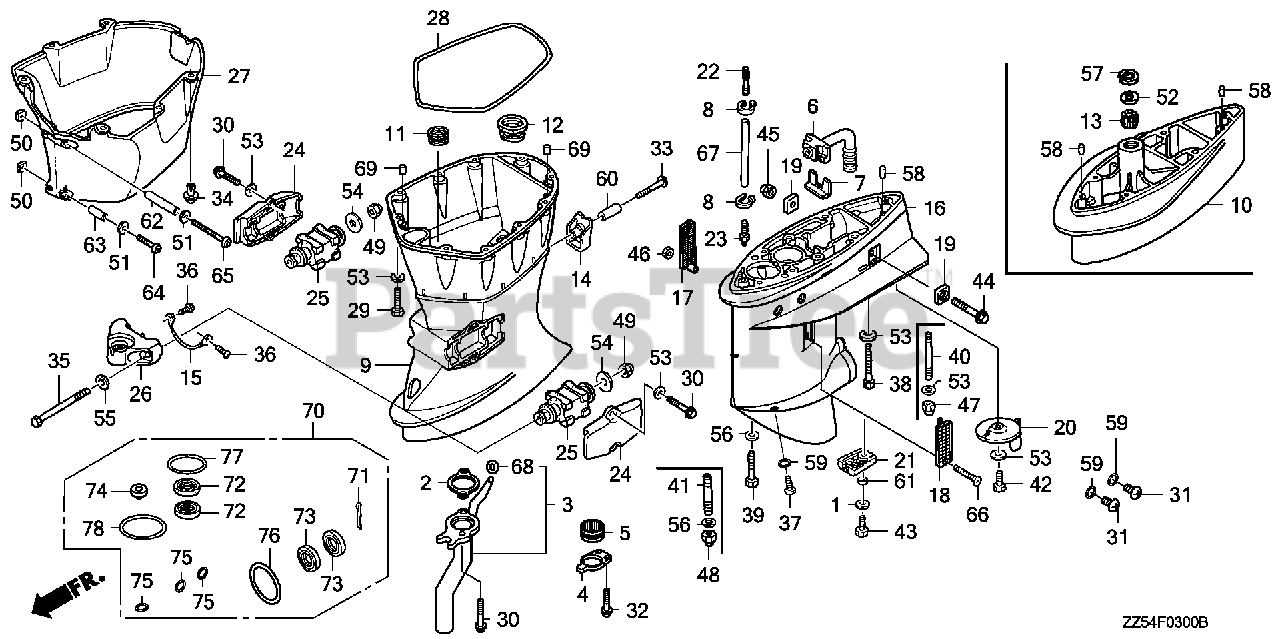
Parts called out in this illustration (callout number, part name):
1	WASHER, PIVOT
2	GASKET, EX. PIPE
3	PIPE KIT, EX.
4	HOLDER, EX. PIPE GROMMET
5	GROMMET, EX. PIPE
6	TUBE, WATER (LOWER)
7	PLATE, RUBBER SETTING
8	BAND, WIRE
9	CASE, EXTENSION *NH282MU* (OYSTER SILVER METALLIC-U)
10	SEPARATOR, EXTENSION *NH282MU* (OYSTER SILVER METALLIC-U)
11	GROMMET, EXTENSION CASE
12	RUBBER, DRAIN PLUG
13	BUSH, VERTICAL SHAFT
14	COVER, DRAIN PLUG *NH282MU* (OYSTER SILVER METALLIC-U)
15	WIRE, LEAD (1.5X116MM)
16	CASE, GEAR *NH282MU* (OYSTER SILVER METALLIC-U)
17	SCREEN, R. WATER
18	SCREEN, L. WATER
19	METAL, ANODE
20	TAB, TRIM *NH282MU* (OYSTER SILVER METALLIC-U)
21	SCREEN, WATER (LOWER)
22	END, NIPPLE
23	NIPPLE, SENSOR
24	HOUSING, R. MOUNTING (LOWER) *NH282MU* (OYSTER SILVER METALLIC-U)
25	RUBBER, MOUNT (LOWER)
26	HOUSING, CENTER MOUNTING (LOWER) *NH282MU* (OYSTER SILVER METALLIC-U)
27	COVER (LOWER) *NH282MU* (OYSTER SILVER METALLIC-U)
28	RUBBER, COVER (LOWER)
29	BOLT, HEX. (8X35)
30	BOLT, FLANGE (8X25)
31	BOLT, OIL CHECK
32	BOLT, FLANGE (6X20)
33	SCREW, SPECIAL (6X35)
34	SCREW, RIVET (8X15)
35	BOLT, HEX. (12X162)
36	SCREW, PAN (6X8)
37	BOLT, DRAIN PLUG
40	BOLT, STUD (8X164)
41	BOLT, STUD (10X132)
42	BOLT, HEX. (8X20)
43	BOLT, HEX. (6X16)
44	BOLT, FLANGE (6X25)
45	NUT, SELF-LOCK (6MM)
46	NUT, SELF-LOCK (5MM)
47	NUT, SELF-LOCK (8MM)
48	NUT, SELF-LOCK (10MM)
49	NUT, SELF-LOCK (12MM)
50	NUT, PLATE (5MM)
51	WASHER, PLAIN (5MM)
52	WASHER (20MM)
53	WASHER, PLAIN (8MM)
54	WASHER, PLAIN (12MM)
55	WASHER, PLAIN (12MM)
56	WASHER, PLAIN (10MM)
57	CIRCLIP (INNER) (30MM)
58	PIN, DOWEL (6X10)
59	O-RING (6.9X1.45)
60	COLLAR, DISTANCE (6X10.5X25)
61	COLLAR, WATER SCREEN (LOWER)
62	COLLAR, DISTANCE (5X7X38)
63	COLLAR, DISTANCE (5X7X23)
64	SCREW, PAN (5X30)
65	SCREW, PAN (5X45)
66	SCREW, OVAL (5X40)
67	BULK HOSE, VACUUM (5X3000) (5X300)
68	GROMMET, EX. BREATHER PIPE
68	O-RING (15X1.9)
69	PIN, DOWEL (6X15)
69	PIN, DOWEL (6X10)
70	CASE KIT, GEAR
71	PIN, SPLIT (4.0)
72	SEAL, WATER (17X30X7)
73	SEAL, WATER (22X35X7)
74	SEAL, WATER (7MM)
75	O-RING (6.9X1.45)
76	O-RING (69X3.1)
77	O-RING (41.7X3.5)
78	O-RING (47X3.1)
